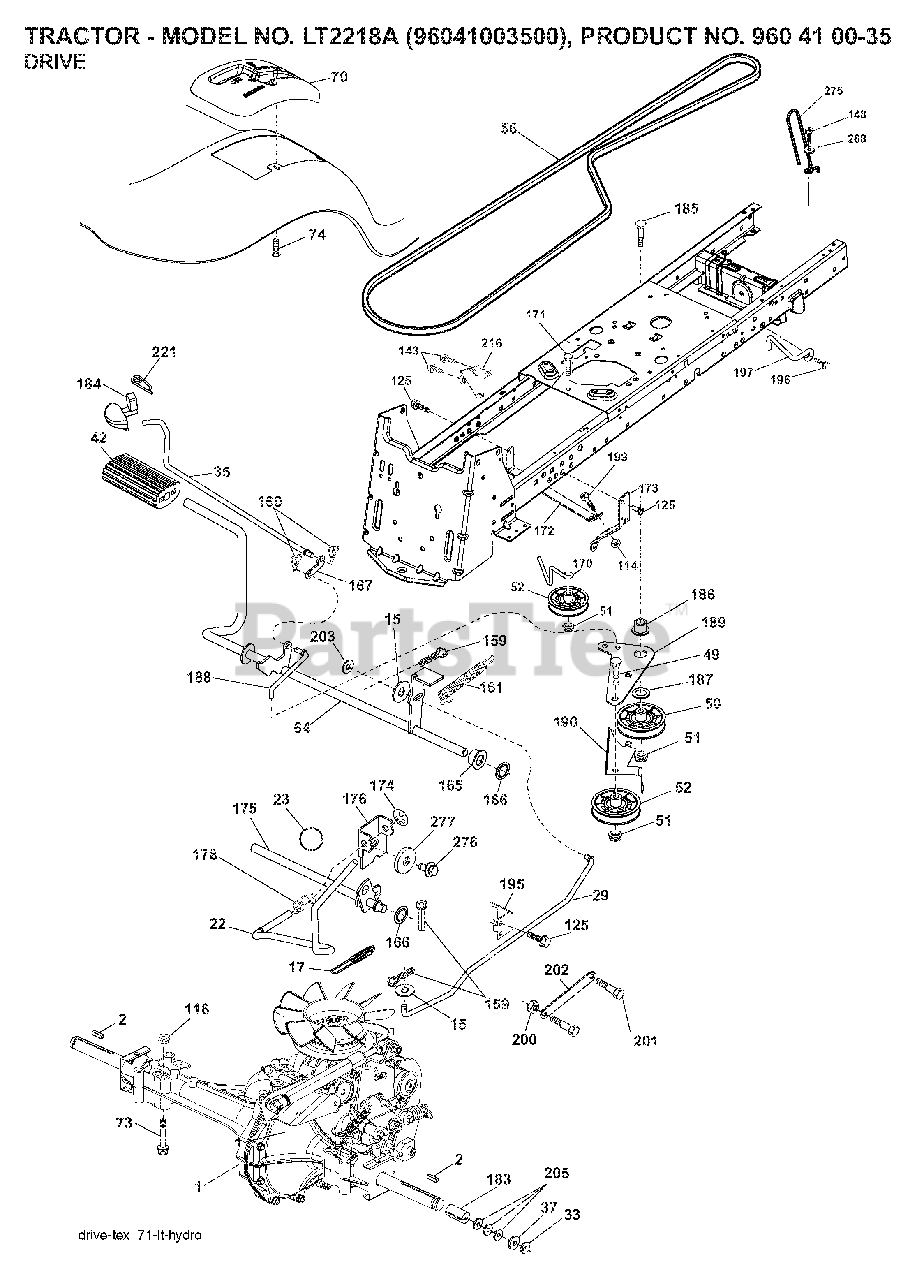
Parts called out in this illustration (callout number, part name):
2	SQUARE KEY
17	SPRING.BRAKE.HG3000/3500
22	ROD.SHIFT.FENDER.TLT.2006
23	PISTOL KNOB
29	ROD.BRAKE.HG-0510
33	E-RING LT
35	ROD.BRKAE.PARKING.STEALTH
42	PEDAL COVER T
49	BOLT
50	IDLER.FLAT.910.OFFSET
51	NUT LOCK FLG 3/8-16 UNC
52	IDLER.V-GROOVE.910.OFFSET
64	SHAFT.ASM.PEDAL.BRAKE.
70	CONSOLE.SHIFT.STL.HYD.BLACK
73	BOLT HEX 5/16-18 GR 5
74	SCREW.HI-LO.CONSOLE
114	NUT.71038.31-18.HEX.NYLOCK
116	NUT LOCK HEX FLANGE 5/16-18
125	SCREW
148	SCREW, 3/8-16X3/4
159	COTTER PIN
160	RETAINER CLIP
161	SPRING.RETURN.CLUTCH.2006
165	LATCH.BRAKE.SPRING
166	NUT.PUSH.625.2006
167	LATCH.BRAKE.SPRING
170	KEEPER.V-IDLER.CENTER.
171	BOLT
172	STRAP.TRQ.LH.FS.HG0510
173	STRAP TORQUE RH
174	NUT.PUSH.500.2006
175	SHAFT.ASM.SHFT.HG0510/
176	ARM.CLEVIS.ROD.SHIFT
178	SPRING.SHIFT.GT2006
183	SPACER AXLE
184	HANDLE.PRKG.BRAKE.STLTH.TX.RED
186	SPACER.RETAINER
187	WASHER 12/32X2X10GA
188	LINK.CLUTCH.GROUND.DRIVE
189	BELLCRANK.GROUND.DRIVE.TEX.
190	KEEPER.BELLCRANK.DRIVE
195	BRKT.ROD.BRAKE.18/20/2
196	SCREW 3/8-16X1
197	LINK.CLUTCH.ANIT-ROTAT
199	BOLT
200	NUT.CENTERLOCK.5/16-
201	BOLT SHOULDER 5/16-18 UNC
203	WASHER
216	BRACKET.PULLEY.IDLER.W/TEX
221	RETAINER.SPRING.CLIP.H
268	WASHER
276	BOLT FIN HEX 7/16-14 X 1
277	WASHER SERRATED
